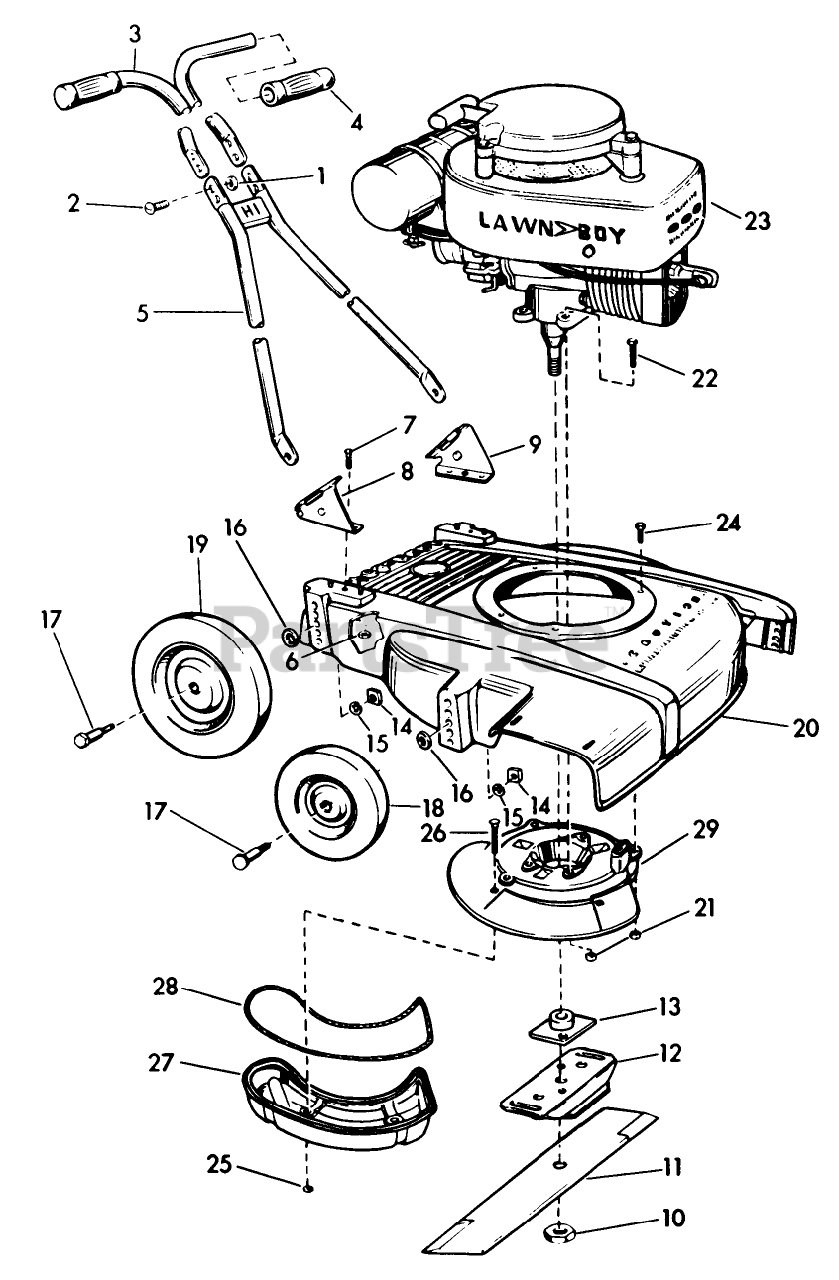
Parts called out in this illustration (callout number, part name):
1	STOP NUT
4	HANDLE GRIP
10	NUT-BLADE
13	PLATE AND COLLAR ASM
15	WASHER, LOCK
20	Housing-18"
25	LOCKNUT E
